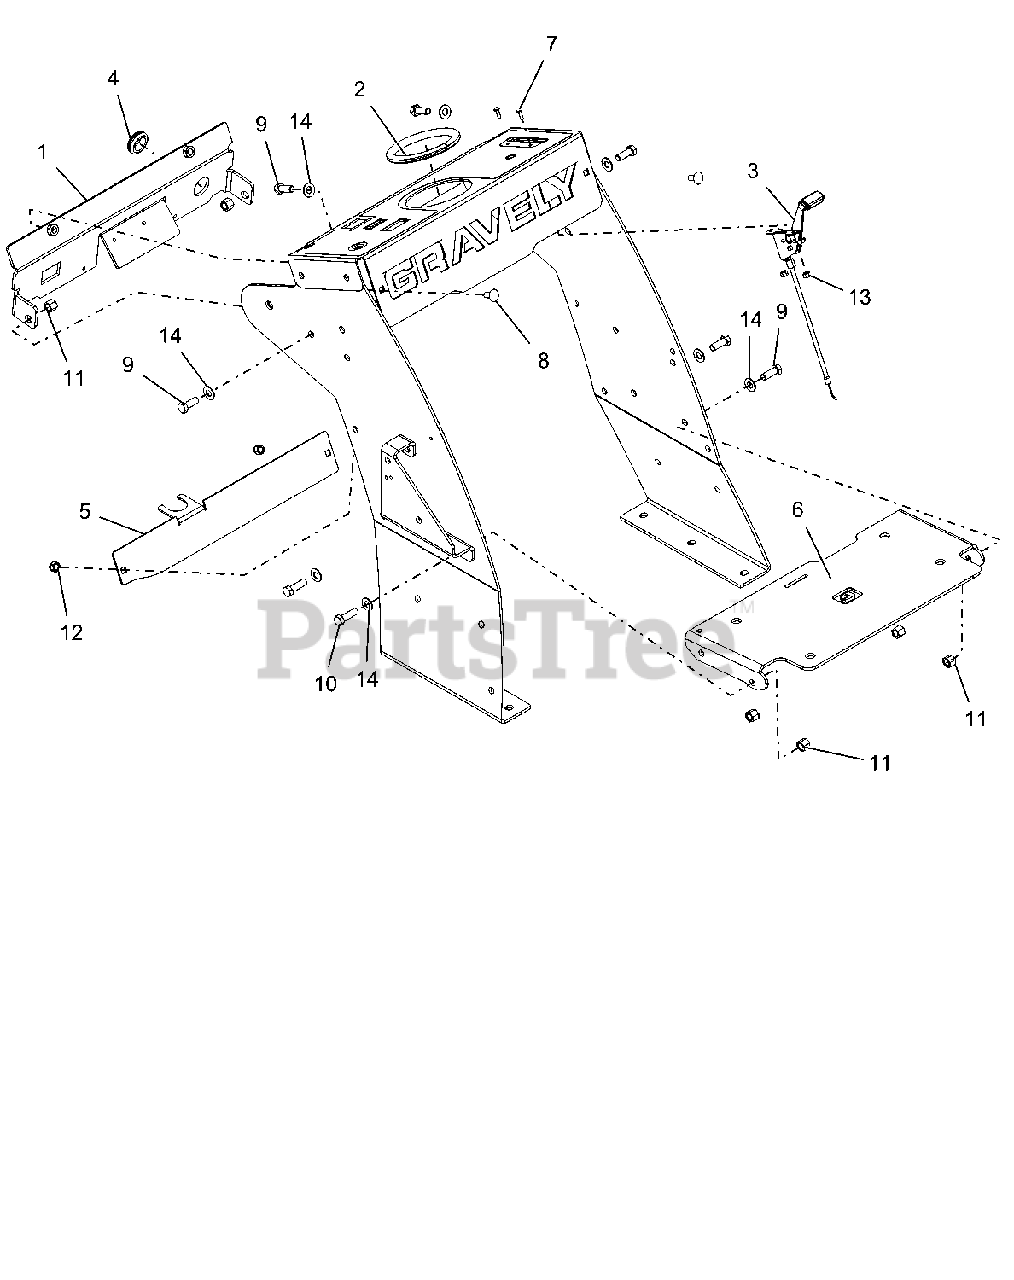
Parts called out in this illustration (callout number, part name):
1	WLDMT, HANDLE BRACE-RED
2	TRIM, RUBBER DEGE 12"
3	CABLE, THROTTLE 49.5"
4	GROMMET:RUB:.88IDx1.38ODX.14GR
5	BRACKET, REMOTE ROV HYDRO-BLACK
6	BRKT, FUEL TANK GRAVELY
7	SCR - PANHDPHLPS 8-32 X .5
8	BLT-RDHDSQNK .31-18X.75 G5 YWZC
9	BLT-HEX .38-16X1.00 GR5 YWZC
10	BLT-HEX .38-16X1.25 GR5 YWZC
11	NUT-LK-NYL .38-16 YWZC
12	NUT-LK-NYL .312-18 YWZC
13	NUT-LK-NYL #8-32 YWZC
14	WSHR-FL-STL.406X.812X.065 YWZ
